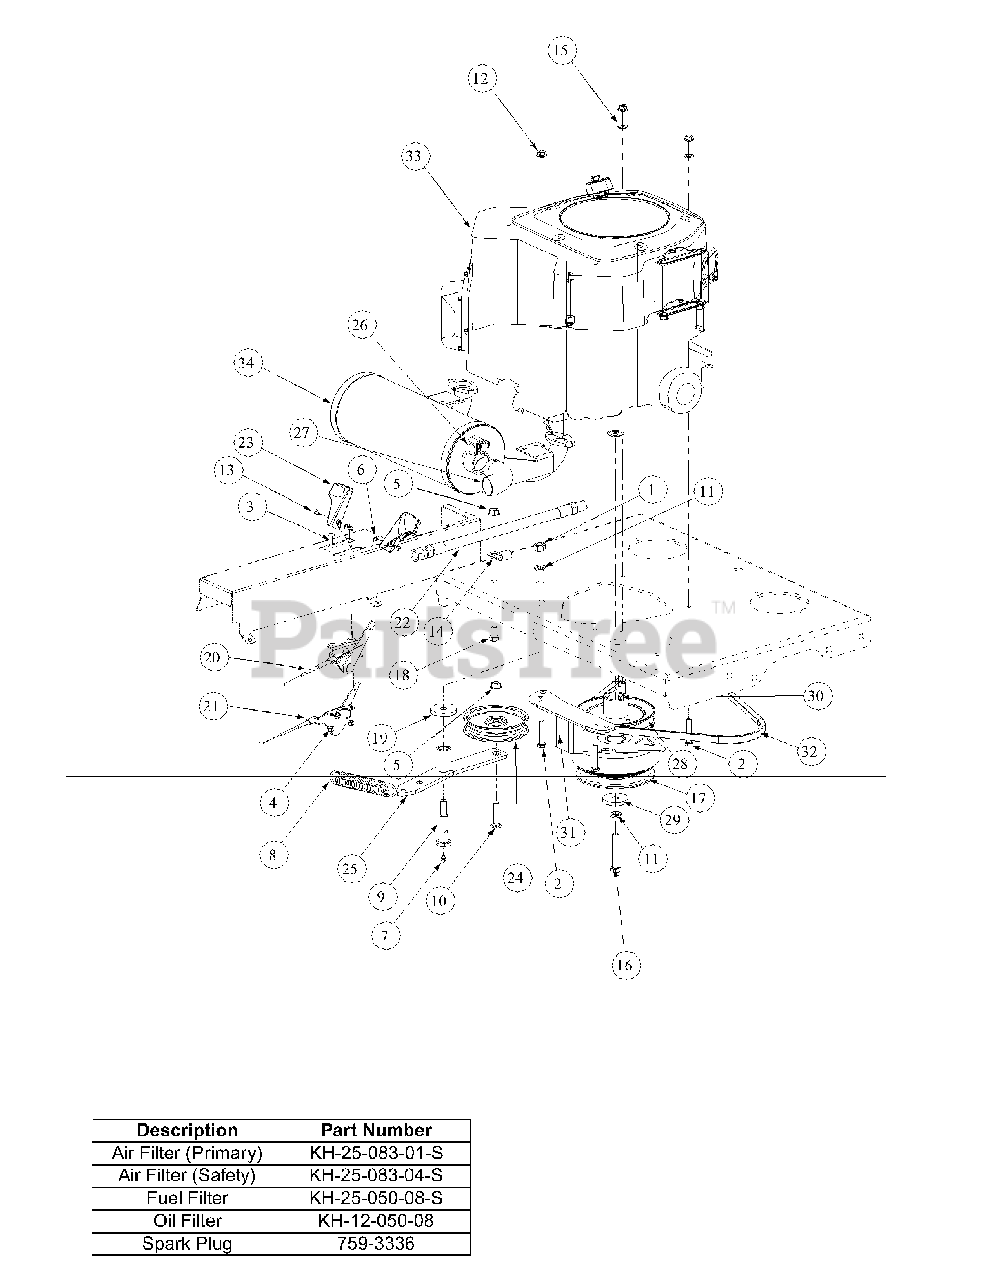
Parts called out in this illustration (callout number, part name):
1	Hex Nut, 7/16-14
2	HHCS, 5/16-18, 1-3/4
3	Round Hd. Machine Screw, 10-32 x 3/4
4	Lock Nut, Nylon Insert, 10-32
5	Flange Lock, Hex Nut, 3/8-16
6	Nut Washer, W/Star, 8-32
7	Grease Fitting, 1/4-28 x 3/16
8	Extension Spring, 1.0 OD x 5.125
9	Shoulder Screw, 7/16-14
10	Hex Carriage Screw, 3/8-16, 1.75
11	Lock Washer, 7/16
12	Hexflange Lock Nut, 5/16-18
13	Machine Screw, 8-32, .375
14	Clip, Heat Shield Cable
15	Flat Washer, 5/16
16	Capscrew, 7/16-20 x 2.50
17	Clutch Brake, 1.125 ID
18	Hex Cap Screw, 3/8-16, .750
19	Flat Washer, 7/16 ID x 1.75 OD x .25
20	Choke Control Cable
21	Throttle Control Cable
22	Oil Drain Hose
23	Control Throttle Knob
24	Flat Pulley with Flanges
25	Engine Idler Arm Assembly
26	Tube Clamp, 1.375
27	Muffler Accessory Exhaust Tube
28	Pump Drive Pulley
29	Flat Washer, 7/16 ID x 1.75 OD x .25
30	Key, 1/4 x 1/4 x 3
31	Retainer Clutch Assembly, Ogura
32	Belt, 51.2 Lg
33	Engine, 27HP Kohler
34	Muffler
